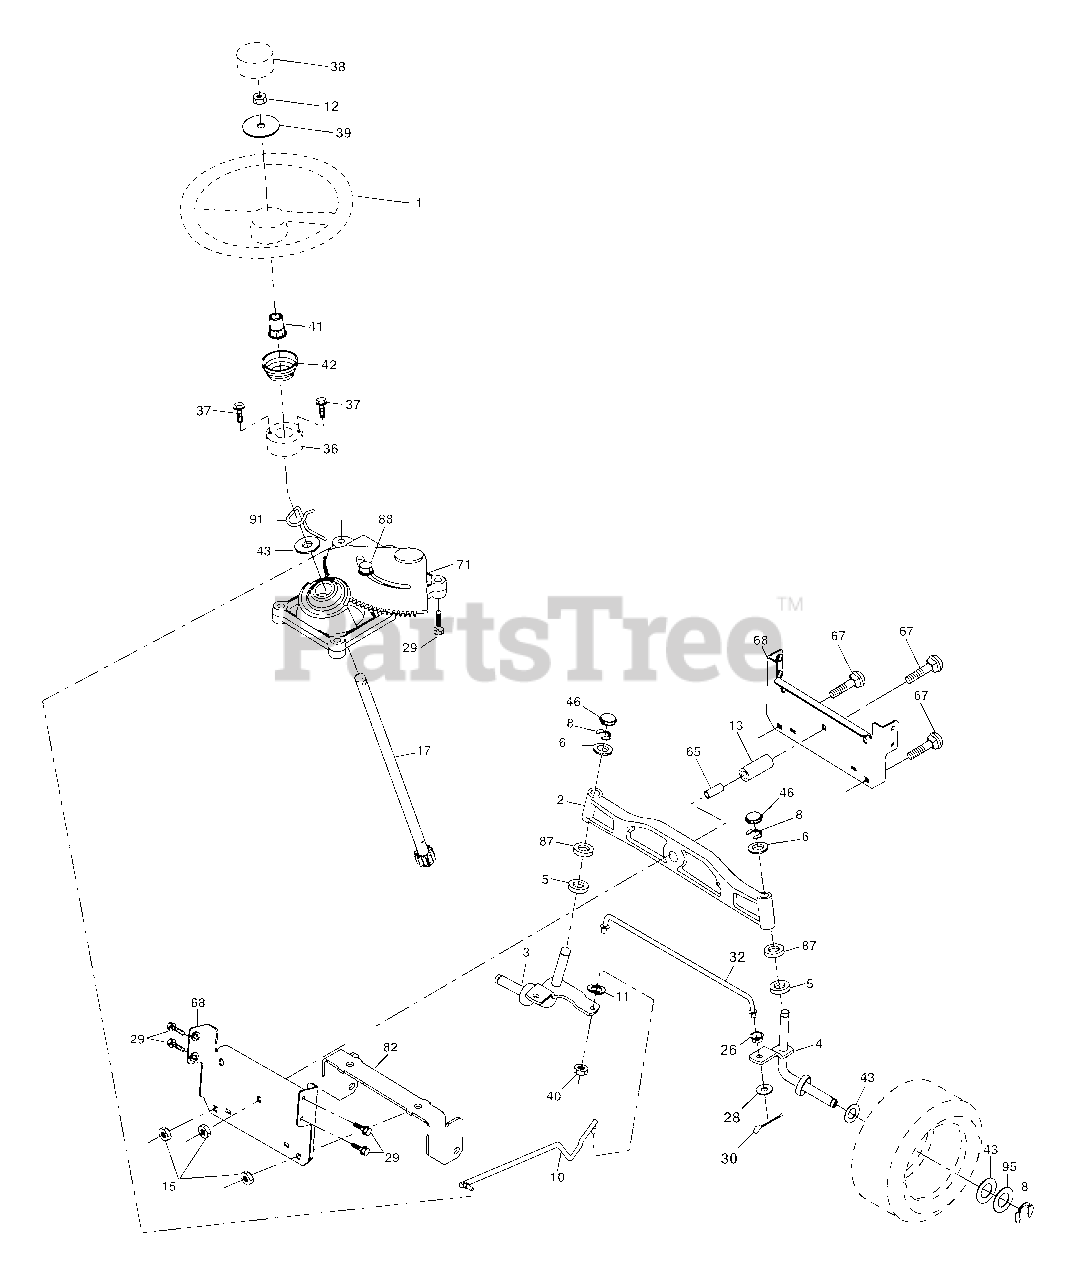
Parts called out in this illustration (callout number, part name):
1	Wheel Steering
2	Axle Asm Cast Iron LT
3	Spindle Asm LH
4	Spindle Asm RH
5	Bearing Race Thrust Harden
6	Washer 25/32 x 1-5/8 x 16 Ga.
8	Ring Klip #t5304-75
10	Link Drag
11	Washer Lock Hvy Hlcl Spr 3/8
12	Nut Hex Jam Toplock 1/2-20 unf
13	Spacer Brg Axle Front
15	Nut Hex Flange Lock
17	Shaft Asm Steering
26	Bushing Link Drag
28	Washer 13/32 x 7/8 x 16 Ga.
29	Screw 3/8-16 x .75
30	Pin Cotter 1/8 x 3/4
32	Rod Tie
36	Bushing Strg
37	Screw
38	Insert Cap Strg Wh
39	Washer 9/16 ID x 2-3/8 OD 12 Ga.
40	Crownlock nut
41	Adaptor Wheel Strg
42	Boot Steering Dash
43	Washer 25/32 x 1 1/4 x 16 Ga.
46	Cap Spindle Fr Top Blk
65	Spacer Brace Axle
67	Bolt RDHD SQNK 3/8-16 x 2 1/4
68	Axle, Brace
71	Steering Asm
82	Bracket Susp Chassis Front
87	Washer Flat .781 x 1-1/2 x .14
88	Bolt Shoulder 7/16-20 unc
91	Clip Steering
95	Washer Harden .739 x 1.637 x 060
